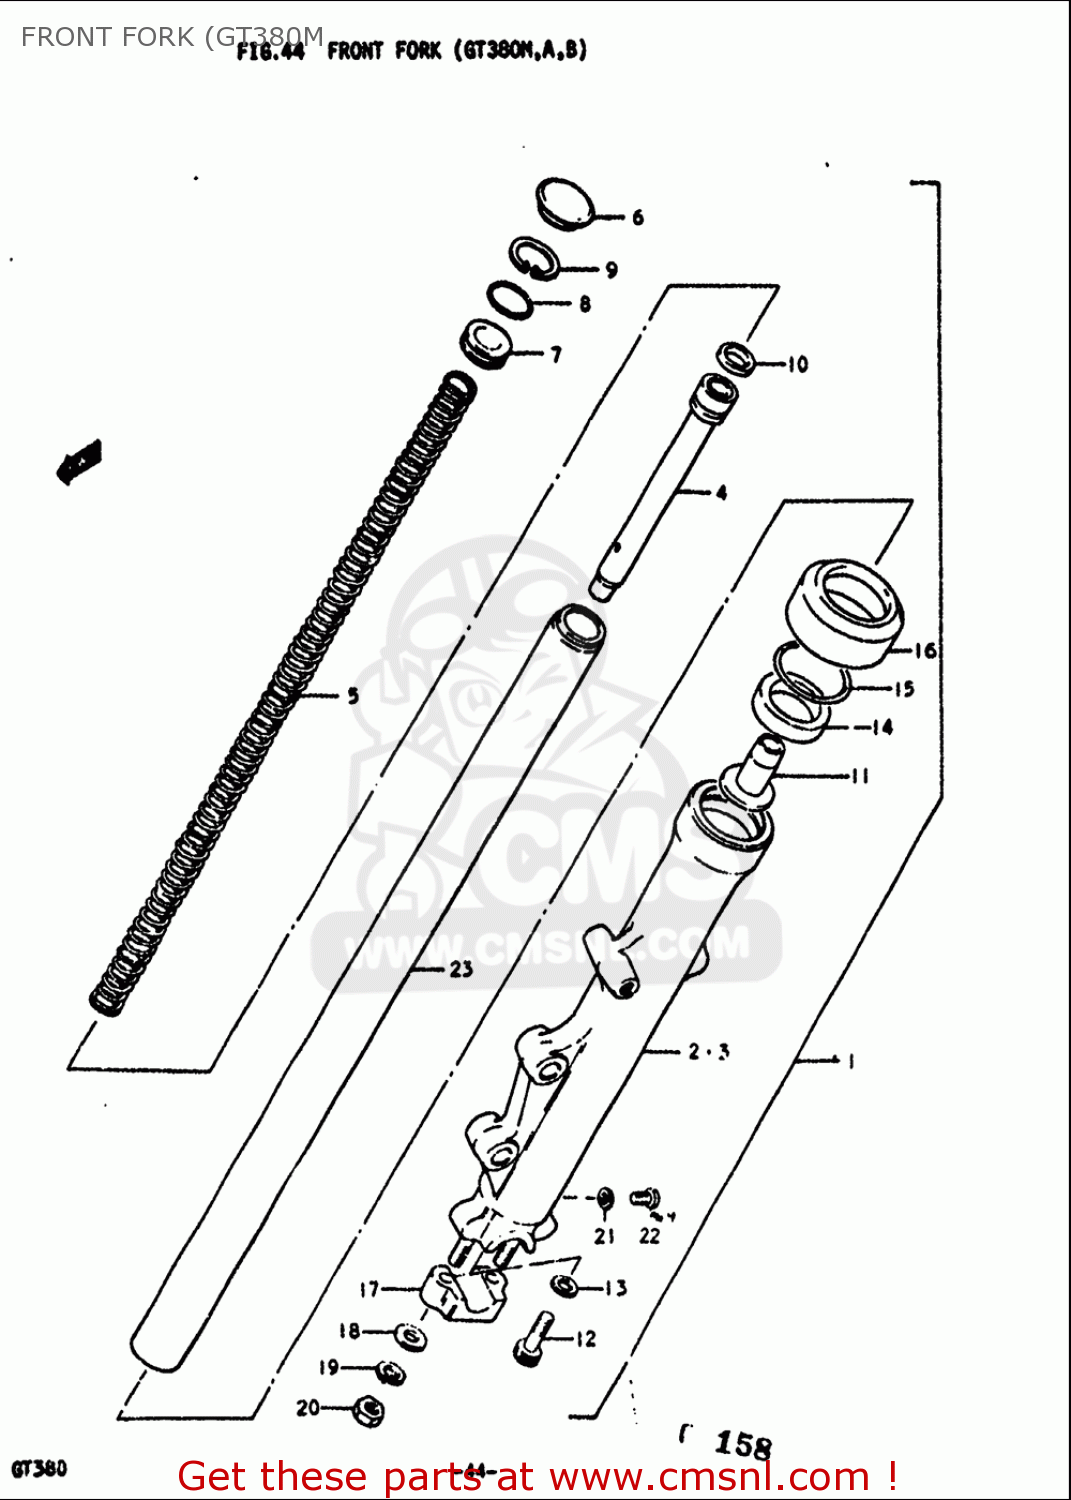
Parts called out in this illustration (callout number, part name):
8	O RING
12	BOLT(8X27)
13	GASKET (NAS)
14	SEAL,OIL
15	RING,OIL SEAL STOPPER
16	DUST SEAL
17	HOLDER,AXLE
18	WASHER
19	WASHER,LOCK
20	NUT
21	GASKET (NAS)
22	SCREW
